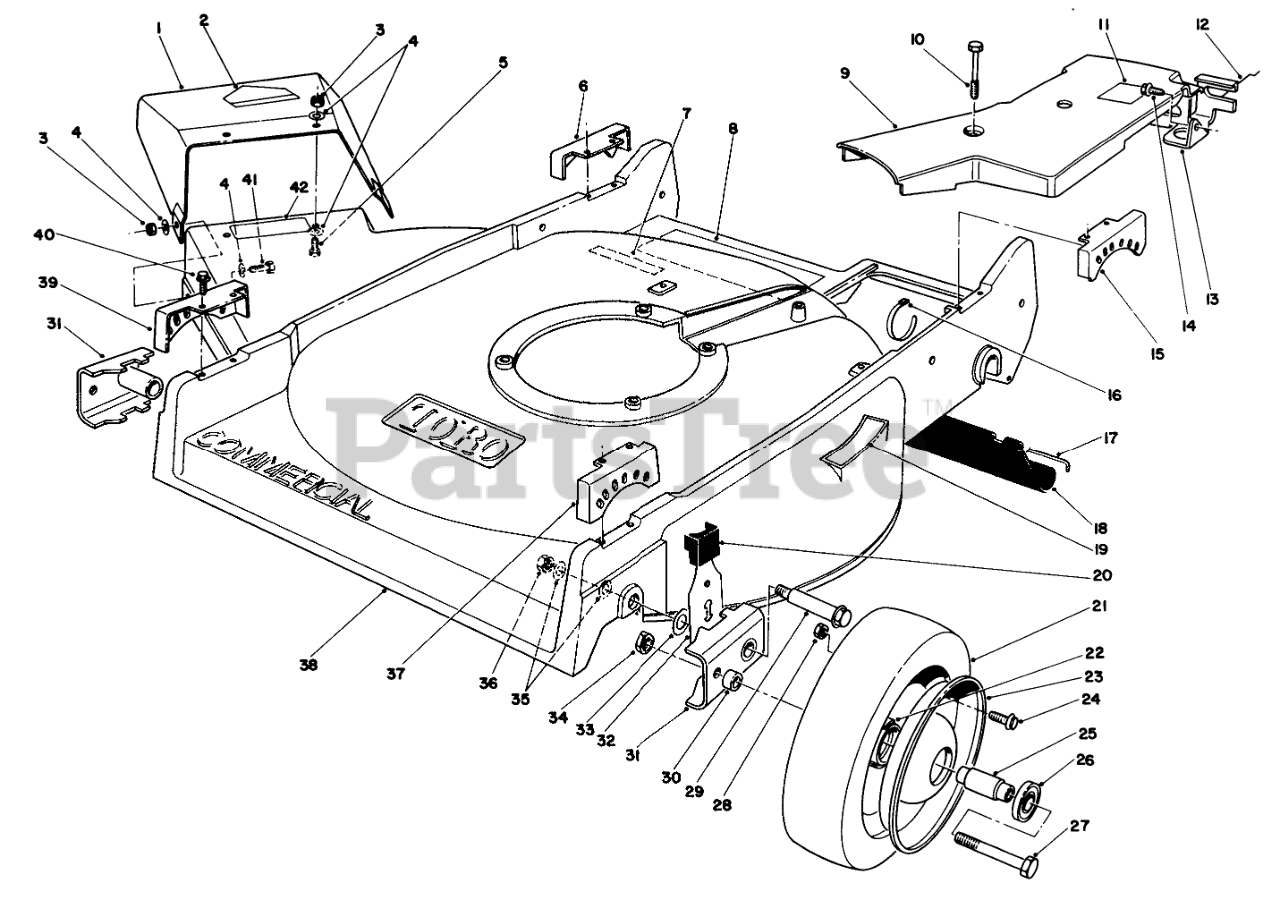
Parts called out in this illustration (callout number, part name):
1	Deflector Assy. (Incl. Ref. #2)
2	DECAL-DANGER
3	NUT-LOCK, NI
4	WASHER-FLAT
5	SCREW-HH
6	QUADRANT-REAR, RH
7	Decal
8	Decal-Safety Instructions
9	Decal-Hot
10	SCREW-HHFTF
11	LABEL-GREASE
12	RETAINER-CABLE
13	Bracket-Traction Adj.
14	SCREW-HWHTF
15	QUADRANT-REAR, LH
16	TIE-CABLE
17	ROD-SHIELD
18	SHIELD-TRAILING
19	DECAL - STEP PAD INT'L
20	KNOB-ARM
22	HUB-BEARING
23	Wheel-Half
24	SCREW-HHF
25	SPACER-BEARING
26	BEARING-WHEEL
27	SCREW-HH
28	NUT-LOCK, NI
29	WHEEL BOLT
30	SPACER-WHEEL
31	ARM-PIVOT, FRONT
32	FRONT SPRING ARM ASM
33	WASHER-THRUST
34	NUT-LOCK, CONE
35	WASHER
36	Nut
37	QUADRANT-FRONT, LH
38	Housing-Commercial (Incl. Ref. #8, 19, & 42)
39	QUADRANT-FRONT, RH
40	SCREW-HWHTF
41	SCREW-HH
42	DECAL-DANGER
